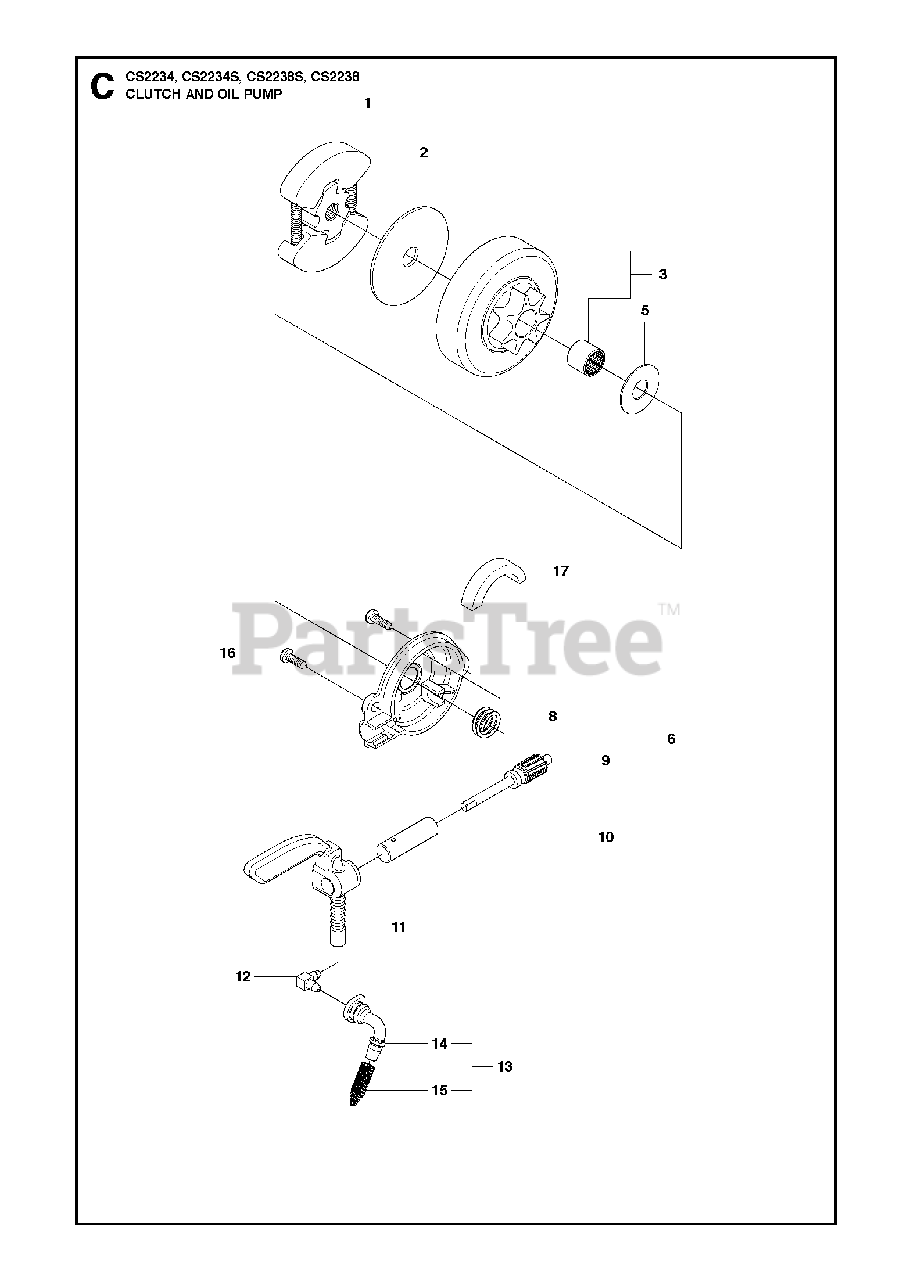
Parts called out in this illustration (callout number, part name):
1	CLUTCH ASSEMBLY
2	FRICTION DISC,CLUTCH 36/41
3	CLUTCH DRUM ASSY
3	ASSY CLUTCH DRUM .325"
5	DUST COVER 36/41
6	OIL PUMP COMPLETE
8	WORM GEAR
9	PLUNGER & GEAR
10	PUMP
11	BLOCK OIL
13	PICK UPS ASSY OIL TANK
15	SCREEN/FILTER
16	SCREW 6-19X.437
